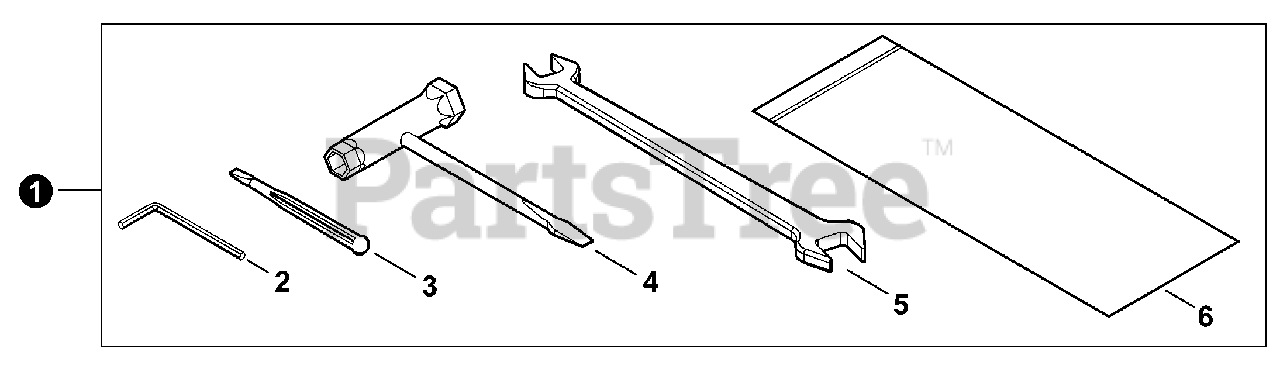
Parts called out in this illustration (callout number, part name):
1	TOOL KIT, SERVICE
2	WRENCH, ALLEN 4MM
3	SCREWDRIVER, PLASTIC
4	T-WRENCH 13×19mm
5	SPANNER 8×10
6	BAG, TOOL
